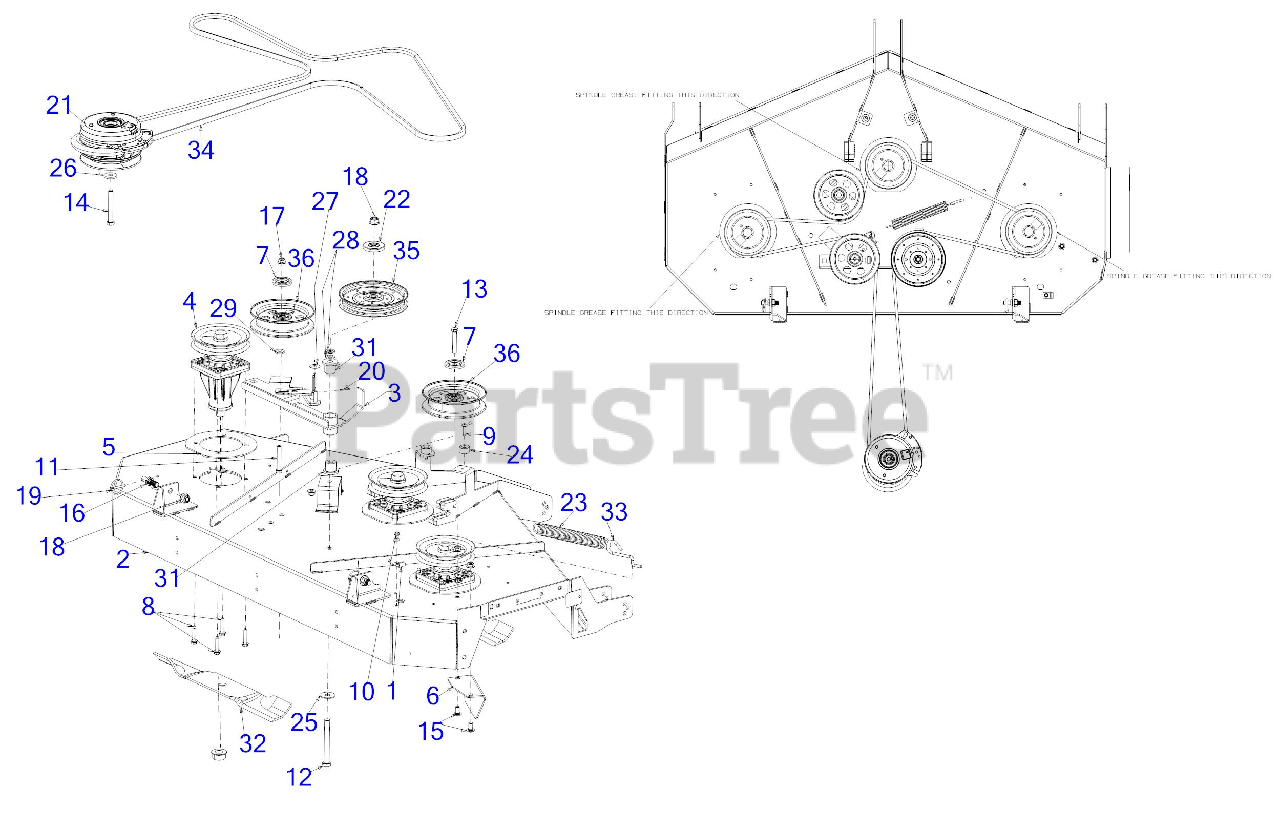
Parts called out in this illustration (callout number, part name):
1	HOOK RETAINER BRACKET
2	54" FAB DECK SHELL
3	DECK IDLER ASSEMBLY
4	BLADE SPINDLE ASSEMBLY (W/PULLEY)
7	PULLEY CAP 1.875 DIA
8	SCREW 5/16-18 x 1.50
9	SCREW 1/4-20 x 1.0
10	SCREW 1/4-20 X.500
11	HEX SCREW-3/8-16X2.5 GR5
12	SCREW 1/2-13 x 4.5 GR 5
13	SCREW 3/8-16 x 2.25 GR5
14	SCREW 7/16-20 x 3.25 GR5
15	CARRIAGE BOLT 3/8-16 x .75
20	COTTER PIN 3/32
21	ELECTRIC PTO CLUTCH
22	PULLEY CAP 1/2"
23	EXTENSION SPRING
25	WASHER .51 x 1.5 x .07
26	FLAT WASHER .445 x 1.248 x .170
27	FLAT WASHER
28	FLAT WASHER
29	FLAT WASHER
31	SHOULDER SPACER
32	19" BLADE (HI LIFT)
33	DECK SPRING HOOK
34	V-BELT B SEC x 154
35	IDLER PULLEY 6.0" DIA
36	5" FLAT IDLER PULLEY
